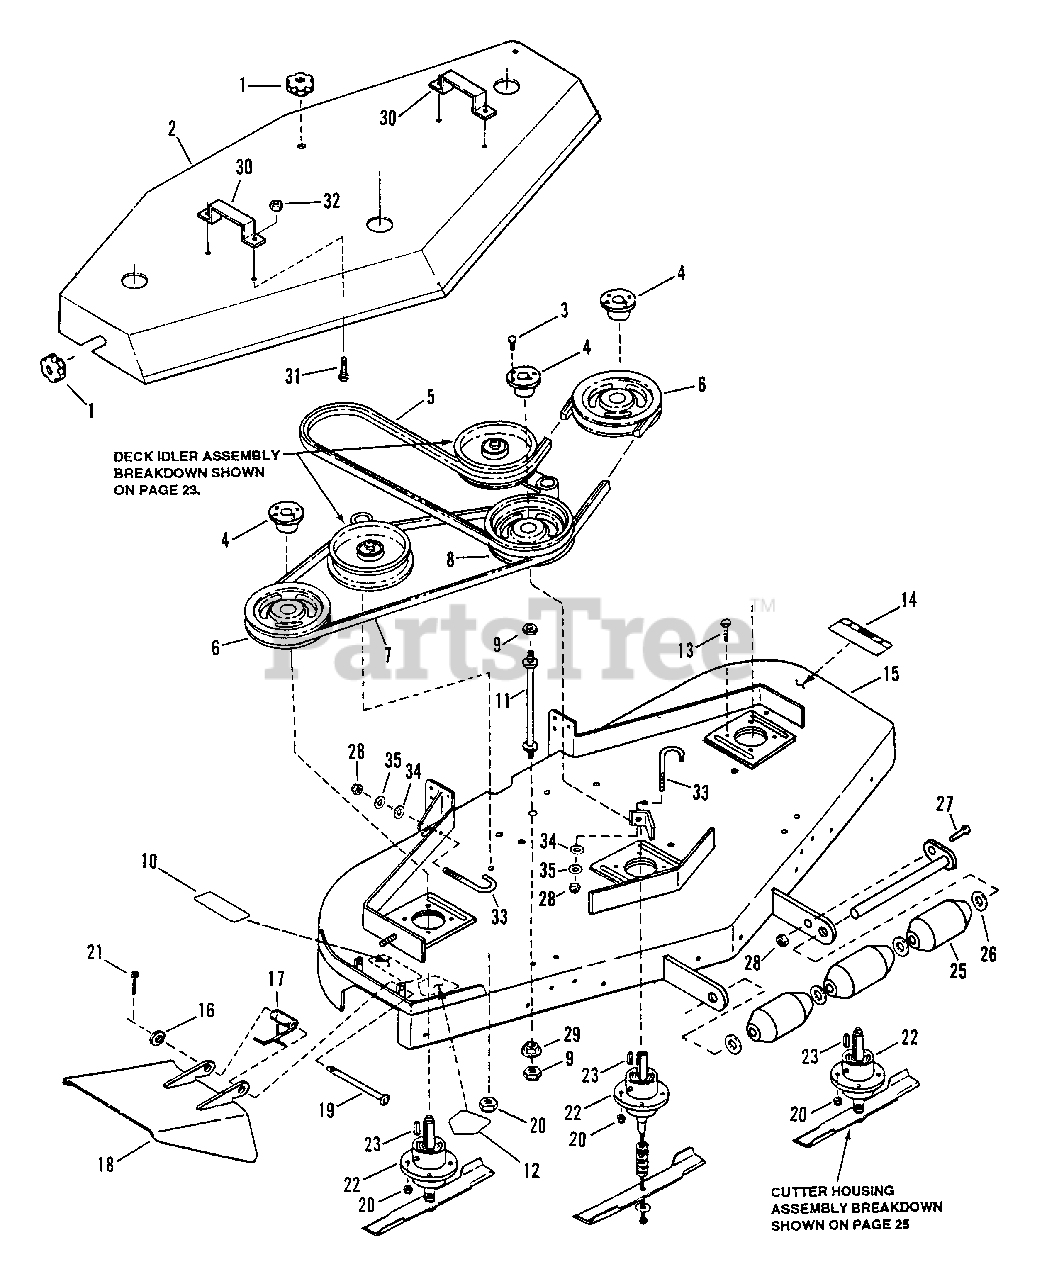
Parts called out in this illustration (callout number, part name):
1	KNOB, Hood
2	HOOD
3	BOLT, 1/4-20 x 7/8" Hex Head Cap
4	BUSHING, Taperlock
5	BELT, Engine To Deck 92.4" E.L. HB
6	PULLEY, Cutter Blade Drive
7	BELT, Blade (48" Deck) 56.0" E.L. HB
8	PULLEY, Cutter Blade Drive (Double Groove)
9	NUT, 5/16-18 HEX NYLON LOCK
10	DECAL, Caution
11	STUD, Hood Mount
12	DECAL, Danger
13	BOLT, 3/8-16 X 1-1/4" GD5 CZ
14	DECAL, Caution
15	WELDMENT, 52" Deck
16	WASHER, 5/16 Flat
17	SPRING, Chute
18	DEFLECTOR, Chute, 52" Deck
19	ROD, Chute Pivot
20	NUT, 3/8-16 HEX NYLON LOCK
21	PIN, 3/32 x 1" Cotter
22	ASSEMBLY, Cutter Housing
23	KEY, Spindle
25	ROLLER
26	WASHER, 5/8 Flat
27	BOLT, 3/8-16 X 1" GD5 CZ
28	NUT, 3/8-16 HEX NYLON LOCK
29	NUT, 5/16-18 Hex Flange Lock
30	HANDLE
31	SCREW, 1/4- x 3/4" Hex Head Cap
32	NUT, 1/4- Hex Lock (Nyloc)
33	"S" ROD
34	WASHER, 3/8" USS
35	WASHER, 3/8 Split Lock
